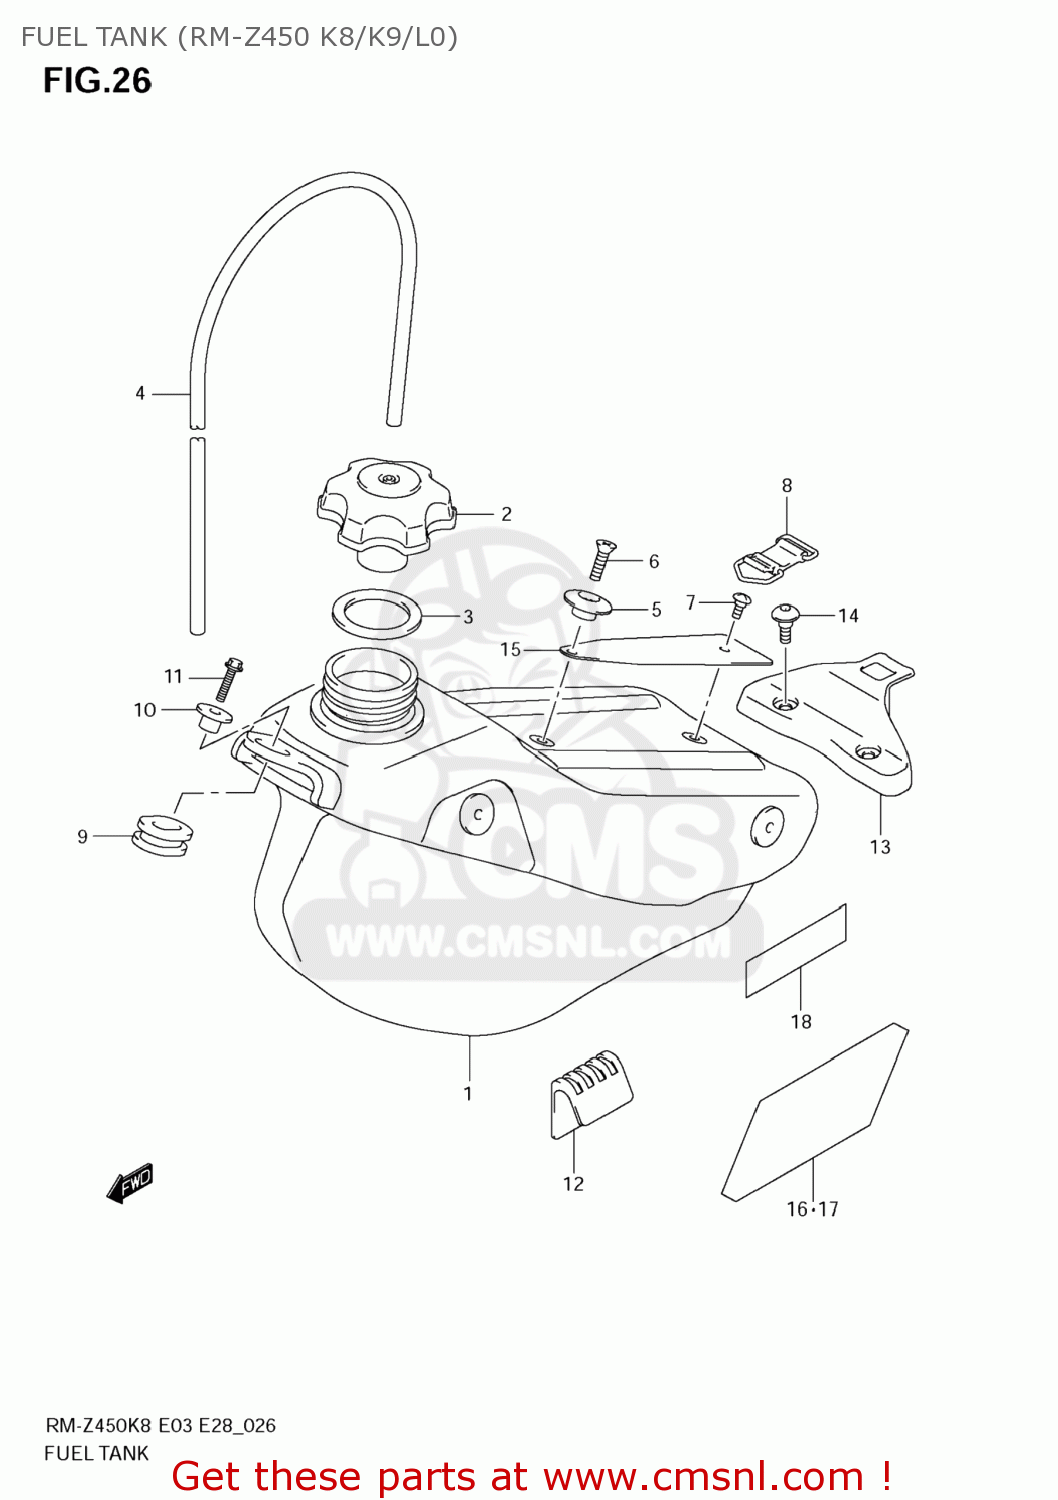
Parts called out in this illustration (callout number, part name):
1	TANK,FUEL
2	CAP,FUEL TANK FILLER
3	GASKET,CAP (NAS)
4	HOSE(5X8.2X600)
5	HOOK,SEAT FR
6	SCREW
7	SCREW(6X13.5)
8	BAND,FUEL TANK RR
9	CUSHION,FUEL TANK FR
10	SPACER
11	BOLT(6X30)
12	CUSHION,TANK SIDE
13	CUSHION,FUEL TANK RR
14	BOLT(5X13)
15	PROTECTOR,FUEL TANK
16	PROTECTOR,RADIATOR,R
17	PROTECTOR,RADIATOR,L
18	PROTECTOR,RADIATOR
